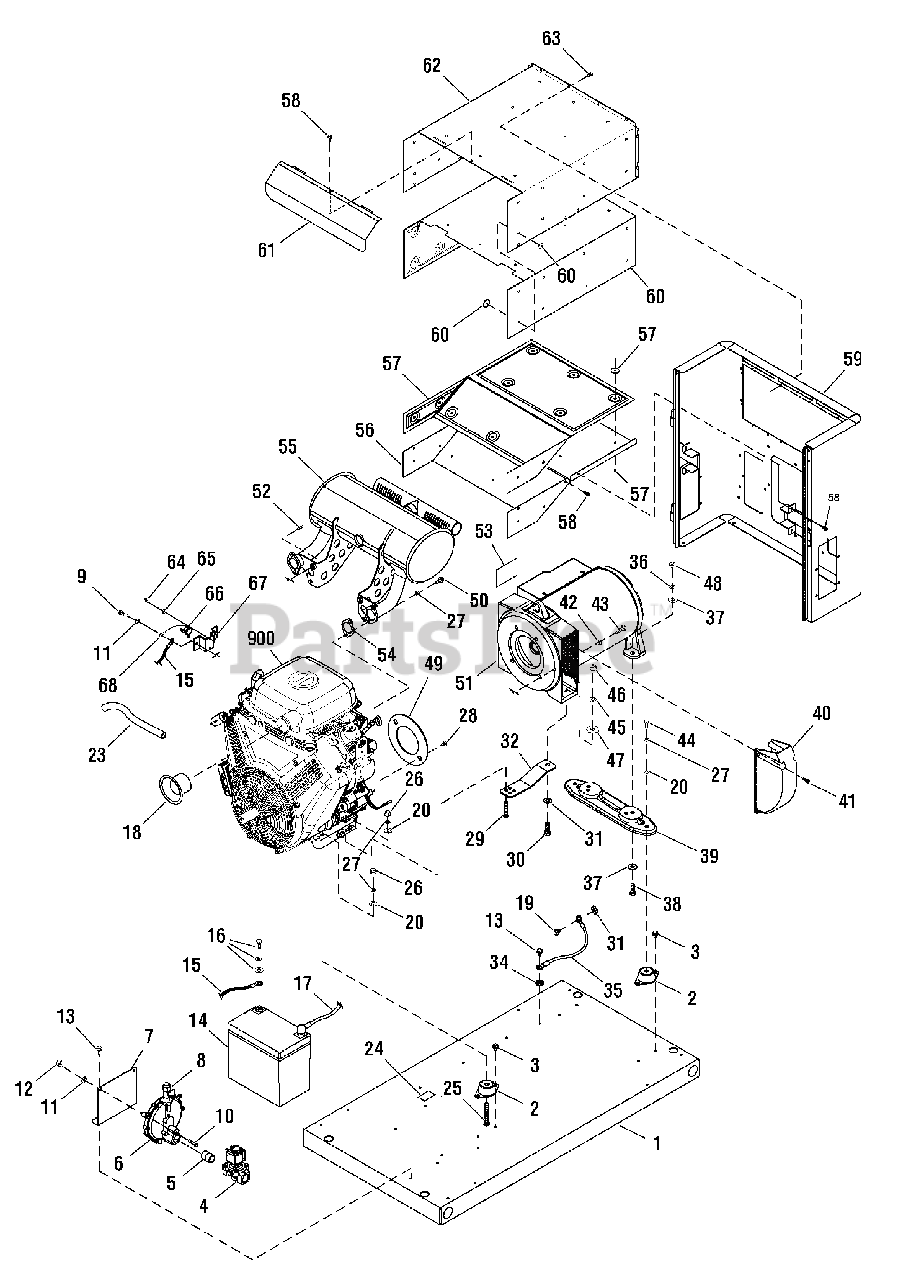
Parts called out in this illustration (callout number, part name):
1	BASE, Mounting
2	MOUNT, Vibration
3	SCREW, Hex Head, Trilobular 5/16-18 x 1/2
4	SOLENOID, Gas Fuel
5	FITTING, Coupling
7	BRACKET, Mounting Solenoid
8	ASSEMBLY, Tee
9	*CAPSCREW, Hex Head, M6-1 x 16
10	*CAPSCREW, Hex Head, M6-1 x 30
11	*WASHER, Lock, 1/4
12	*NUT, M6-1
13	SCREW, Hex Head, Trilobular, 1/4-20 x 1/2
16	KIT, Battery Hardware
18	TUBE, Air Cleaner
19	*CAPSCREW, Hex Head, M6-1 x 12
20	*WASHER, Flat, 5/16 - M8
23	HOSE, Oil Drain
24	DECAL, Oil Drain
25	*CAPSCREW, Hex Head, Full Thread, 5/16-18 x 2-1/2
26	*NUT, 5/16-18
27	*WASHER, Lock, 5/16 - M8
28	*CAPSCREW, Hex Head, Sems, 5/16-24 x 3/4
29	*CAPSCREW, Hex Head, 5/16-18 x 2
30	*CAPSCREW, Hex Head, M12 - 1.75 x 35
31	*WASHER, M12
32	SUPPORT, Engint / Alternator, Black
34	*WASHER, Shakeproof Ext. M6-1/4
36	*WASHER, Lock, M10
37	*WASHER, Flat, M10
38	*CAPSCREW, Hex Head, M10 - 1-1/2 x 30
39	BRACKET, Mounting Alternator, Black
41	*SCREW, Phillips Head, M5-0.8 x 20
42	*WASHER, Lock, 3/8
43	*CAPSCREW, Hex, 3/8-16 x 1-1/4
44	*CAPSCREW, Hex Head, 5/16-18 x 3/4
45	*WASHER, Lock, M12
46	*NUT, Hex, M12 - 1-3/4
47	*WASHER, Flat, M12
48	*NUT, M10 - 1-1/2
49	DISK, Engine Air
50	SCREW
51	ALTERNATOR ASSEMBLY
53	DECAL, Caution Hot Surface
56	BASE, Muffler Box
57	KIT, Insulation, Muffler Base
58	CRIMPTITE, 10-24 x 1/2
59	ASSEMBLY, Bulkhead, Alternator End w/Insulation
60	KIT, Insulation, Muffler Box
61	COLLECTOR, Muffler Box
62	BOX, Muffler Top
63	SCREW. 10-32 x 5/8
64	*SCREW, Phillips Head, 4-40 x 0.19
65	*WASHER, Lock, #4
66	SWITCH, Oil Temp
67	PLATE, Switch Oil Temp
70	DECAL, Requirements, Fuel
900	**ENGINE
